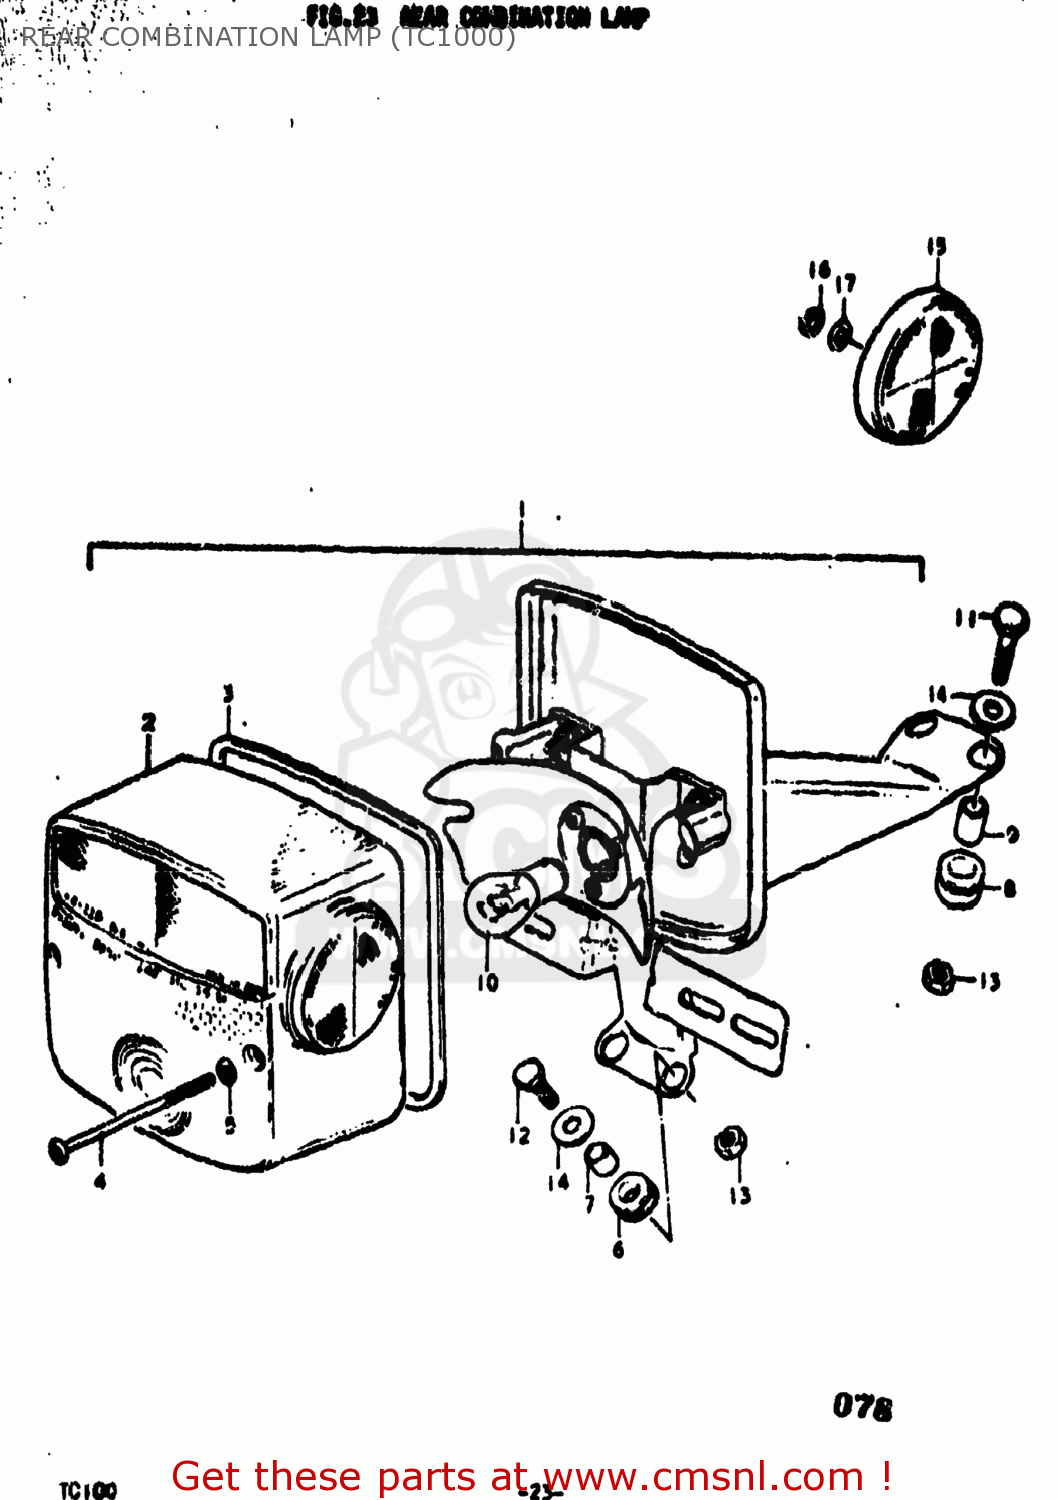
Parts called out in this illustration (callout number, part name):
1	LAMP ASSEMBLY,REAR COMBINATION
2	LENS,REAR COMBINATION LAMP
3	GASKET (NAS)
4	SCREW
5	GASKET (NAS)
6	CUSHION
7	SPACER,REAR COMBINATION LAMP
8	CUSHION
9	SPACER,REAR COMBINATION LAMP
10	BULB(6V32/3CP,STANLEY)
11	BOLT
12	BOLT
13	NUT
14	WASHER (6.5X20X1.2)
15	REFLEX REFLECTOR,FR
16	LOCK WASHER
17	WASHER
